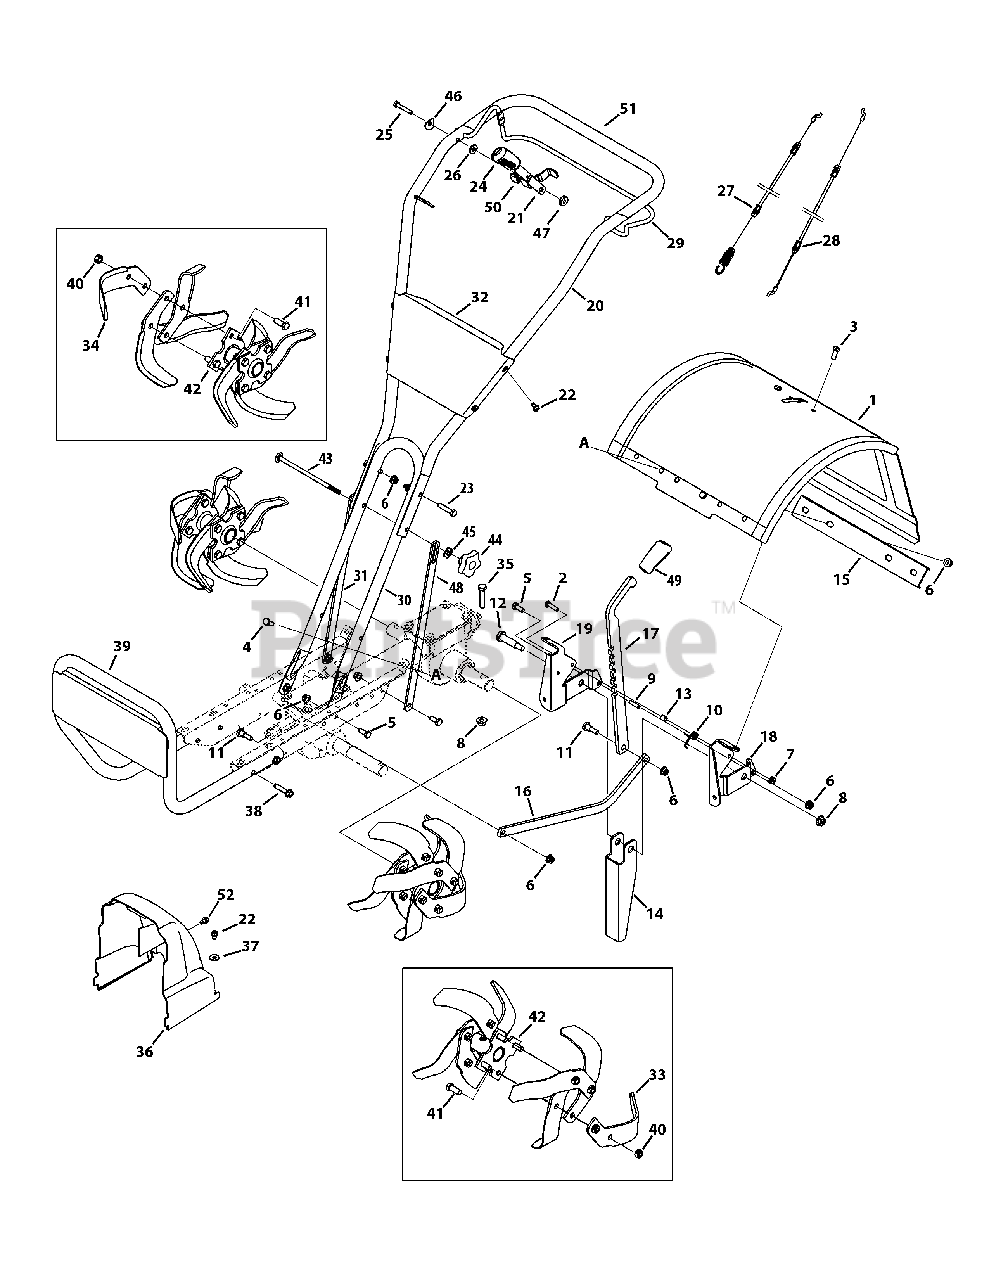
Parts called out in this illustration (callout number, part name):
1	Tine Shield Assembly
2	Hex Head Screw, 1/4-20 x 100
3	Screw, 5/16-18 x 0625
4	Hex Head Washer, 5/16-18 x 875
5	Hex Head Screw, 5/16-18 x 75
6	Flangelock Nut, 5/16-18
7	Flangelock Nut, 1/4-20
8	Flangelock Nut, 3/8-16
9	Spring Pin, 1/4 DIA x 100 LG
10	Torsion Spring
11	Screw, Shoulder, 5/16-18 x 405 x 435
12	Screw, Shoulder, $r 498 x 1635
13	Spacer, Split, 350 x 268 x 375
14	Stop Reverse Arm
15	Support Channel Bracket
16	Depth Drag Bar
17	Depth Adjuster Bar
18	LH Tail Bracket
19	RH Tail Bracket
20	Upper Handle Assembly
21	Reverse Handle Assembly
22	Screw, 1/4-20 x 0500
23	Hex Head Screw, 5/16-18 x 150
24	Reverse Handle Grip
25	Hex Head Screw, 1/4-20 x 162
26	Flat Washer, 265 x 938 x 120
27	Forward Cable
28	Reverse Cable
29	Clutch Bail
31	Support Handle Bracket
33	RH Bolo Tine
34	LH Bolo Tine
35	Hex Head Screw, 3/8-16 x 175
36	Belt Cover
37	Washer, Flat, 28 x 74 x 063
38	Screw, 5/16-18 x 150
39	Bumper
40	Nut, Hexlock, 3/8-16
41	Hex Head Screw, 3/8-16 x 100
42	Tine Holder Assembly
43	Carriage Bolt, 5/16-18 x 675
44	Knob, 5/16-18
45	Washer, 326 x 875 x 145
46	Washer, Saddle, 320 x 93 x 060
47	Spacer, 375 x 165
48	Support Handle Bracket
49	Handle Grip
50	Reverse Handle Grip
51	Handle Grip
52	Self Tapping Screw, 1/4-14 x 625
